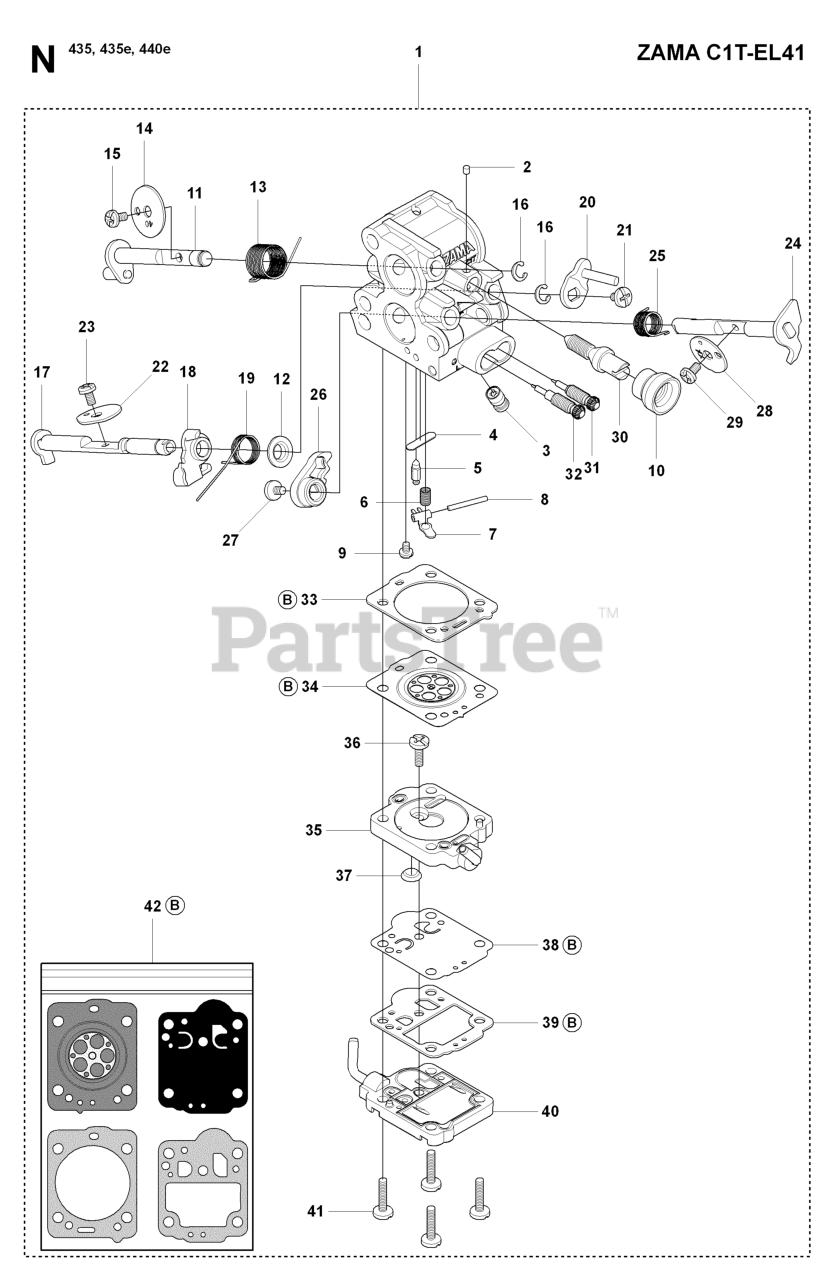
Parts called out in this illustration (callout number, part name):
1	CARBURETOR
3	NOZZLE ASSY
5	INLET NEEDLE
6	SPRING
8	PIN RETAINING SCREW
10	CAP ZAMA 0051034
11	SHAFT ASSY
12	COLLAR ZAMA 005020
17	CHOKE SHAFT ASSY
24	THROTTLE SHAFT ASSY
42	GASKET KIT
